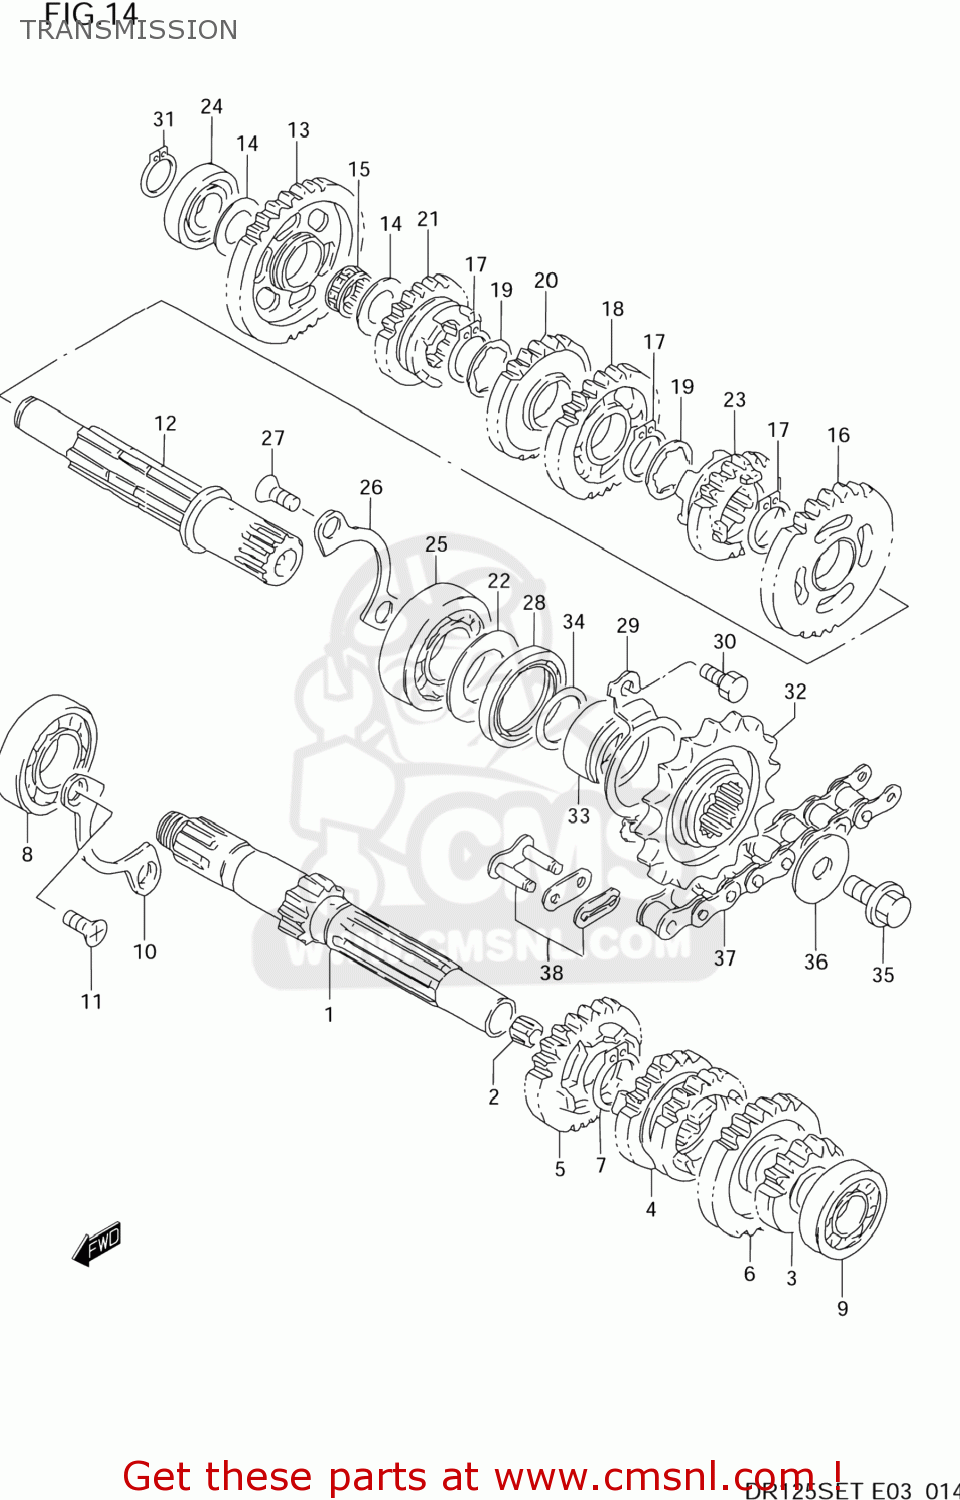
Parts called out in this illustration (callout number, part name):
1	SHAFT,COUNTER
2	BUSH
3	GEAR,SECOND DRIVE
4	GEAR,THIRD & FOURTH DRIVE,N
5	GEAR,FIFTH DRIVE
6	GEAR,SIXTH DRIVE
7	CIRCLIP
8	BEARING(20X47X14)
9	BEARING
10	RETAINER,DRIVE SHAFT BEARING
11	SCREW
12	SHAFT,DRIVE
13	GEAR,FIRST DRIVEN
14	WASHER
15	BEARING(15X19X7.8)
16	GEAR,SECOND DRIVEN
17	CIRCLIP
18	GEAR,THIRD DRIVEN
19	WASHER,LOCK
20	GEAR,FOURTH DRIVEN
21	GEAR,FIFTH DRIVEN
22	WASHER,OIL SEALING
23	GEAR,SIXTH DRIVEN
24	BEARING(15X36X12)
25	BEARING(22X50X14)
26	RETAINER,DRIVE SHAFT BEARING
27	BOLT
28	SEAL,OIL(30X40X6)
29	RETAINER,DRIVESHAFT O
30	SCREW
31	CIRCLIP
32	SPROCKET,ENGINE(NT:16)
33	SPACER,ENGINE SPROCKET
34	O RING(D:2.5,ID:21)
35	BOLT
36	WASHER
37	CHAIN ASSEMBLY,DRIVE
38	JOINT SET,CHAIN
